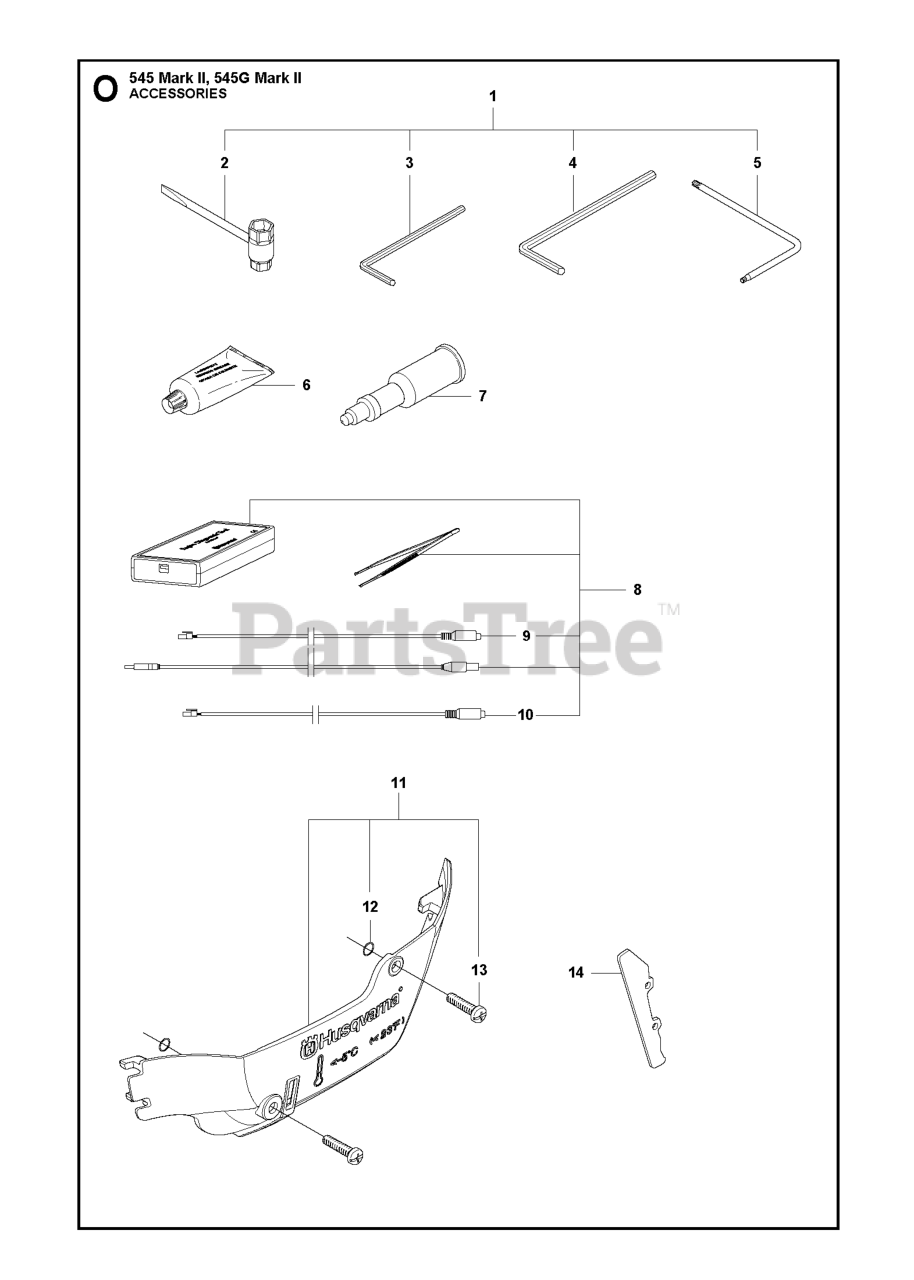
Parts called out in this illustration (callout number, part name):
2	COMBINATION WRENCH
3	L-KEY WRENCH
6	GREASE
7	Grease Gun
8	DIAGNOSTIC TOOL KIT
9	CABLE ASSY
10	CABLE ASSY
11	WINTER KIT 545/550 MARK II
